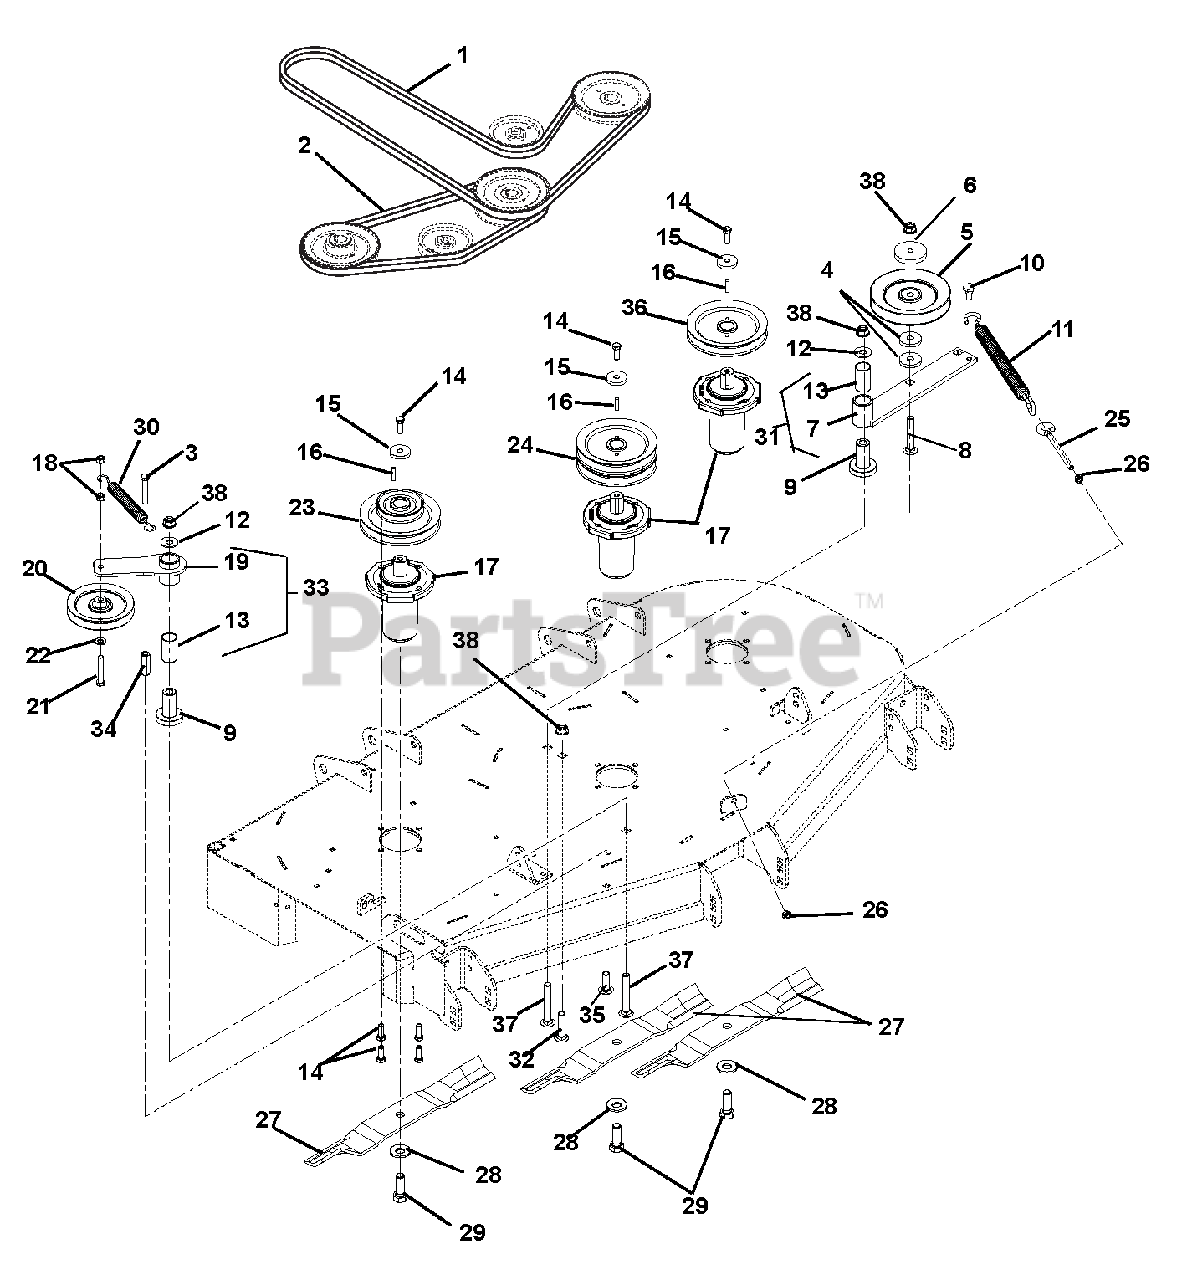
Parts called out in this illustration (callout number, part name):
1	HEX BELT, BB-WRAPPED
2	V-BELT, B-COGGED
3	@BLT-HEX .38-16X1.50 GR5 YWZC
4	WSHR-FL-STL .515X1.625X.250 YZ
5	PLY-V 6.0 X .500 ID SNGL BRG.
6	CAP, IDLER BEARING SEALING
7	IDLER PIVOT ARM WMT - BLACK
8	@BLT-RDHDSQNK .50-13X3.00 G5YZ
9	BEARING, PEDESTAL
10	BLT,SHLDR EP .38-16X.30 HEX YZ
11	SPRING,EXT TO 08300513
12	WSHR-FL-STL .531X1.250X.10 YWZ
13	BSHG, 1.00 X 1.125 X 1.937
14	BLT-HEX .38-16X1.0 GR8 YZ EP30
15	WSHR,FLT STL.406X1.50X.245YWZC
16	KEY, SQ .25X.25X1.00 RC 40-50
17	ASSEMBLY, SPINDLE
18	@NUT-LK-CTR .38-16 YWZC
19	WMT, IDLER PIVOT ARM
20	SHV, .38"ID X 5.00"OD V-IDLER
21	@BLT-HEX .38-16X2.25 GR5 YWZC
22	@WSHR-FL-STL.406X.812X.065 YWZ
23	SHV, DBL 1"IDX6.00"OD & 3.50"
23	SHV, DBL 1"IDX6.75" & 4.25"OD
24	SHEAVE, DOUBLE 1"ID X 6.00"OD
24	SHEAVE, DOUBLE 1"ID X 6.75"OD
25	BOLT, .38-16X4.50 .62 DIA EYE
26	NUT-HEX-JAM .375-16 YWZC
27	BLADE, 18"
27	BLADE, 20.5"
28	WSHR-BLVL .669X1.535X.138
29	BLT-HEX .62-18X1.75 GR8 YWZC
30	SPRING, EXTENSION
31	ASSEMBLY, PTO IDLER PIVOT ARM
32	BLT-RDHDSHSQNKFT.50-13X1.50 G5
33	ASM, IDLER PIVOT ARM
34	NUT COUPLING .375-16X1.75
35	@BLT-RDHDSHSQNK.38-16X1.0 G5YZ
36	SHEAVE, SINGLE 1"ID X 6.00" OD
36	SHEAVE, SINGLE 1"ID X 6.75"OD
37	@BLT-RHDSSQNK .50-13X3.50 G5YZ
38	@NUT-LK-NYL-FLG .50-13 YWZC
